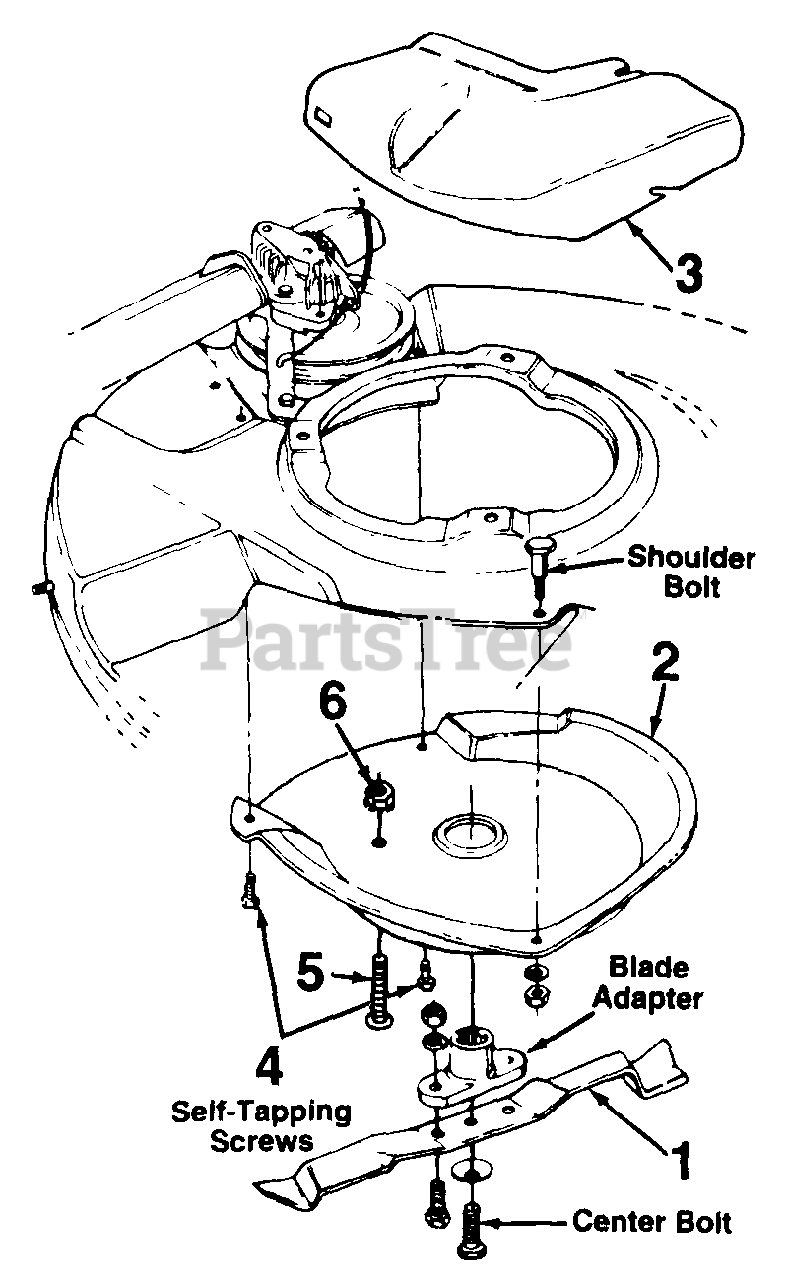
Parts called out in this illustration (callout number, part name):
1	Mulching Blade
4	Self-Tapping Screw
5	Phillips Scr. 1/4-20 x 1.5" Lg.
6	Hex Sems Nut 1/4-20 Thd.
